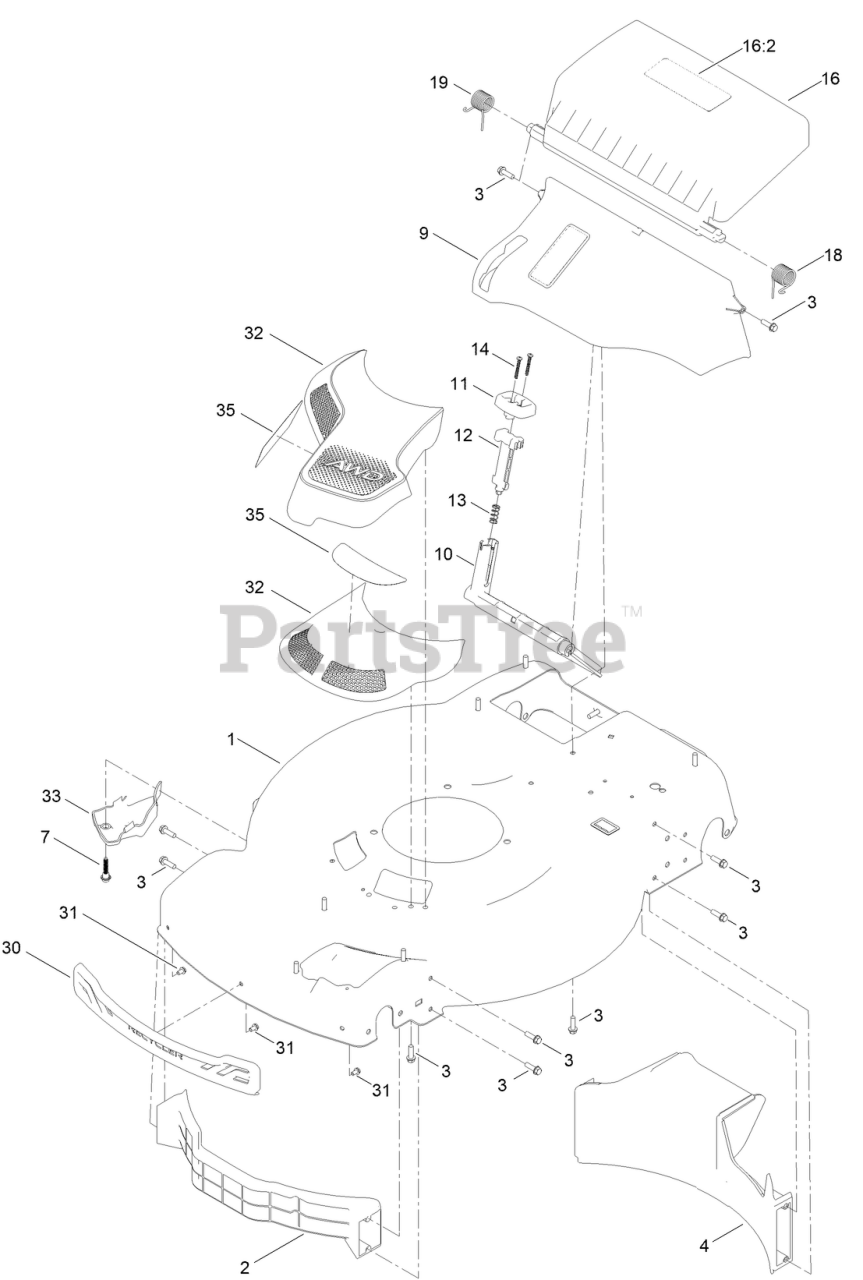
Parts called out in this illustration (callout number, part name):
1	HOUSING ASM
2	BAFFLE-FRONT, DOMESTIC
3	SCREW-HWH
4	BAFFLE-REAR, RWD
7	SCREW-SHOULDER,HWH
9	ASM-CHUTE, IN MOLD
10	DEFLECTOR-RECYCLE
11	KNOB-RECYCLE
12	LATCH-RECYCLE
13	SPRING-COMPRESSION
14	SCREW-PPH
16	ASM-REAR DOOR, IN MOLD
16:2	ARTWORK-DOOR, IN-MOLD
18	SPRING-TORSION, LH
19	SPRING-TORSION, RH
30	BUMPER-FRONT
31	SCREW-PLASTIC, HWH
32	ASM-INTAKE, RWD
33	COVER-INTAKE, BOTTOM
